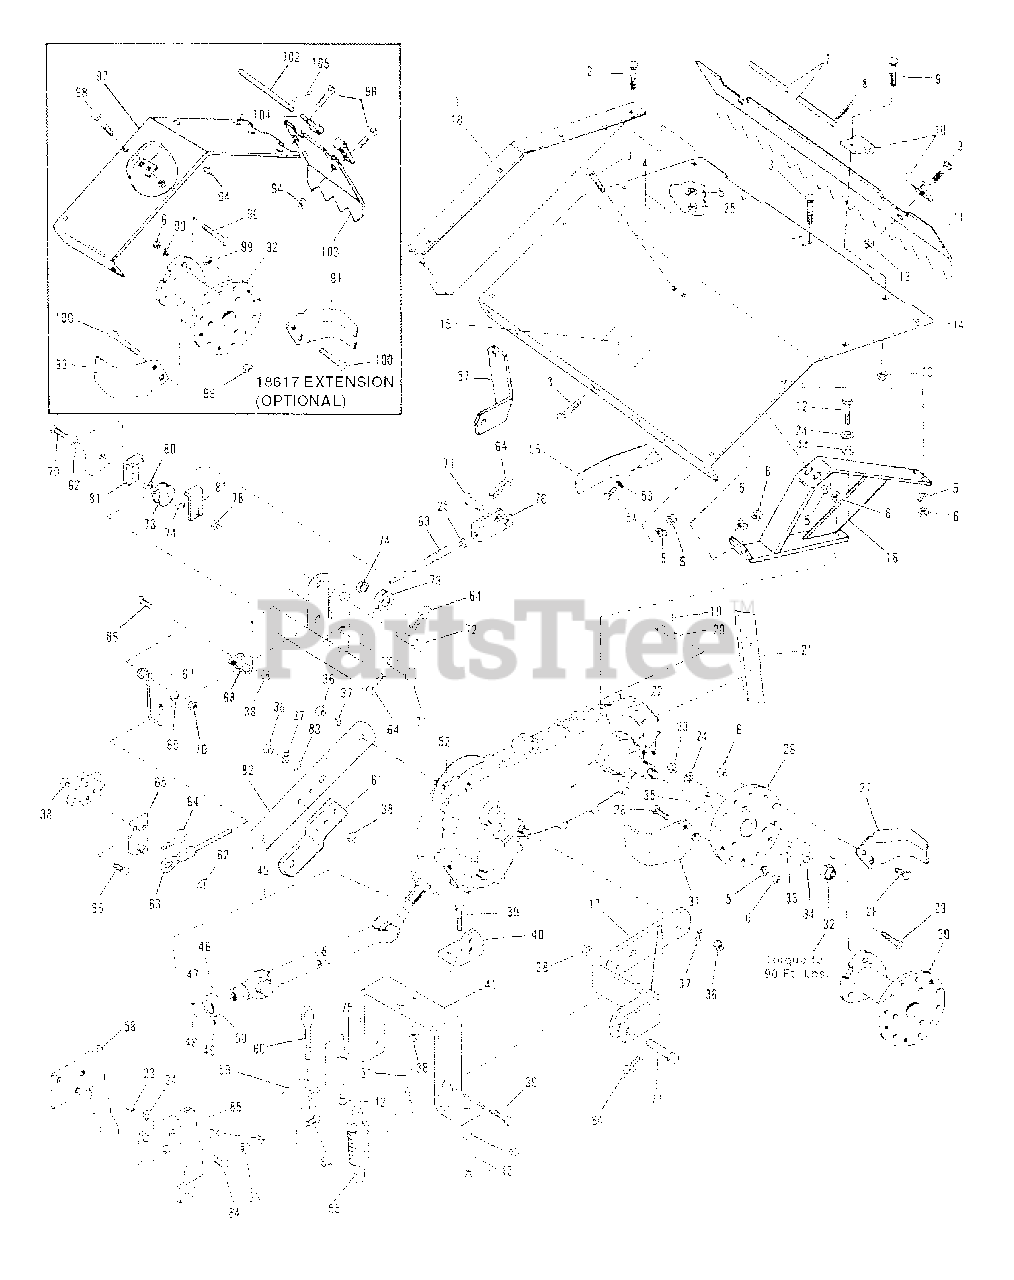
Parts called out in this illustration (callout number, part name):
1	Hood, Right Side
2	Carriage Bolt, 3/8-16 x 314 Sh. Neck
3	Carriage Bolt, 3/8-16 x 1
4	Decal (Logo)
5	Lockwasher, 3/8
6	Lock Nut, 3/8-16
7	Hinge Pin
8	Cotter Pin, 3/32 x 3/4
9	Carriage Bolt, 5/16-16 x 3/4
10	Hinge
11	Leveling Board
12	Hex Screw 1/2-13 x 1-1/4
13	Nut, Flange 5/16-18
15	Decal (Caution)
16	Support Assembly
17	Hitch Arm Assembly
18	Hood, Left Side
19	Cotter Pin, 1/8 x 1
20	Clevis Pin
21	Shoe Center
22	Woodruff Key, 5/16 x 1
23	Nut, 1/2-13
24	Lockwasher, 1/2
25	Nut, 3/8-16
26	Tiller Hub
27	Bend Tire, Left Hand
28	Capscrew, 3/8-16 x 1-1/4
29	Capscrew, 1/2-13 x 1-3/4
31	Send Tine, Right Hand
32	Lock Nut, 5/8-18
33	Spacer Washer
34	Special Washer
35	Sleeve
36	Nut, 5/8-11
37	Lockwasher, 5/8
38	Flange Nut 3/8-16
39	Flange Screw 3/8-16 x 1-3/4
40	Cable Anchor Bracket
41	Lift, Bracket
42	Hex Nut 5/16-18
43	Flat Washer, 5/16
44	Flat Washer, 1/2
45	Drive Shaft Assembly
46	Groove Pin, 3/16 x 1/2
47	Thrust Washer
48	Return Spring
49	Groove Pin, 3/16 x 3/8
50	Locking Collar
51	Eye Bolt
52	Pipe Plug
53	Shakeproof Washer, 3/8
54	Capscrew, 3/8-16 x 1
55	Extension Spring
56	Support Bracket L.H.
57	Support Bracket R.H.
58	Hitch Arm Assembly R.H.
59	Spring support
62	Flat Washer 1/2
63	Lift Cable
64	Spring Pin
65	Lift Arm Assembly
66	Flange Screw 3/8-16 x 1
67	Cable Guide (Hydra Models)
68	Cable Guide (Gear Models)
69	Flat Washer 3/8 (Hydra Models)
70	Lock Nut 3/8-16 (Hydra Models)
71	Clevis Pin
72	Clevis Pin
74	Spacer
75	Spring Bracket
76	Yoke Assembly
77	Clevis Pin
78	Flange Nut 1/2-13
79	Hex Screw 1/2-13 x 2-1/2
80	Spacer (Hydra Models)
81	Cable Retainer (Hydra Models)
82	Arm Support
83	Flat Washer
84	Hex Screw 1/2-13 x 1-1/4
85	Hitch Arm Assembly L.H.
90	Lockwasher, 1/2
92	Spacer
93	R.H. Bend Tine
94	Hex Nut, 5/16-18
96	Hex Head Capscrew, 1/2-13 x 1-3/4
97	Hood Extension
98	Carriage Bolt, 5/16-18 x 3/4
99	Lock Nut, 3/6-16
100	Hex Head Capscrew, 3/8-16 x 1-1/4 H.T.
102	Hinge Pin
103	Leveling Board Extension
104	Hinge
105	Cotter Pin, 3/32 x 3/4
